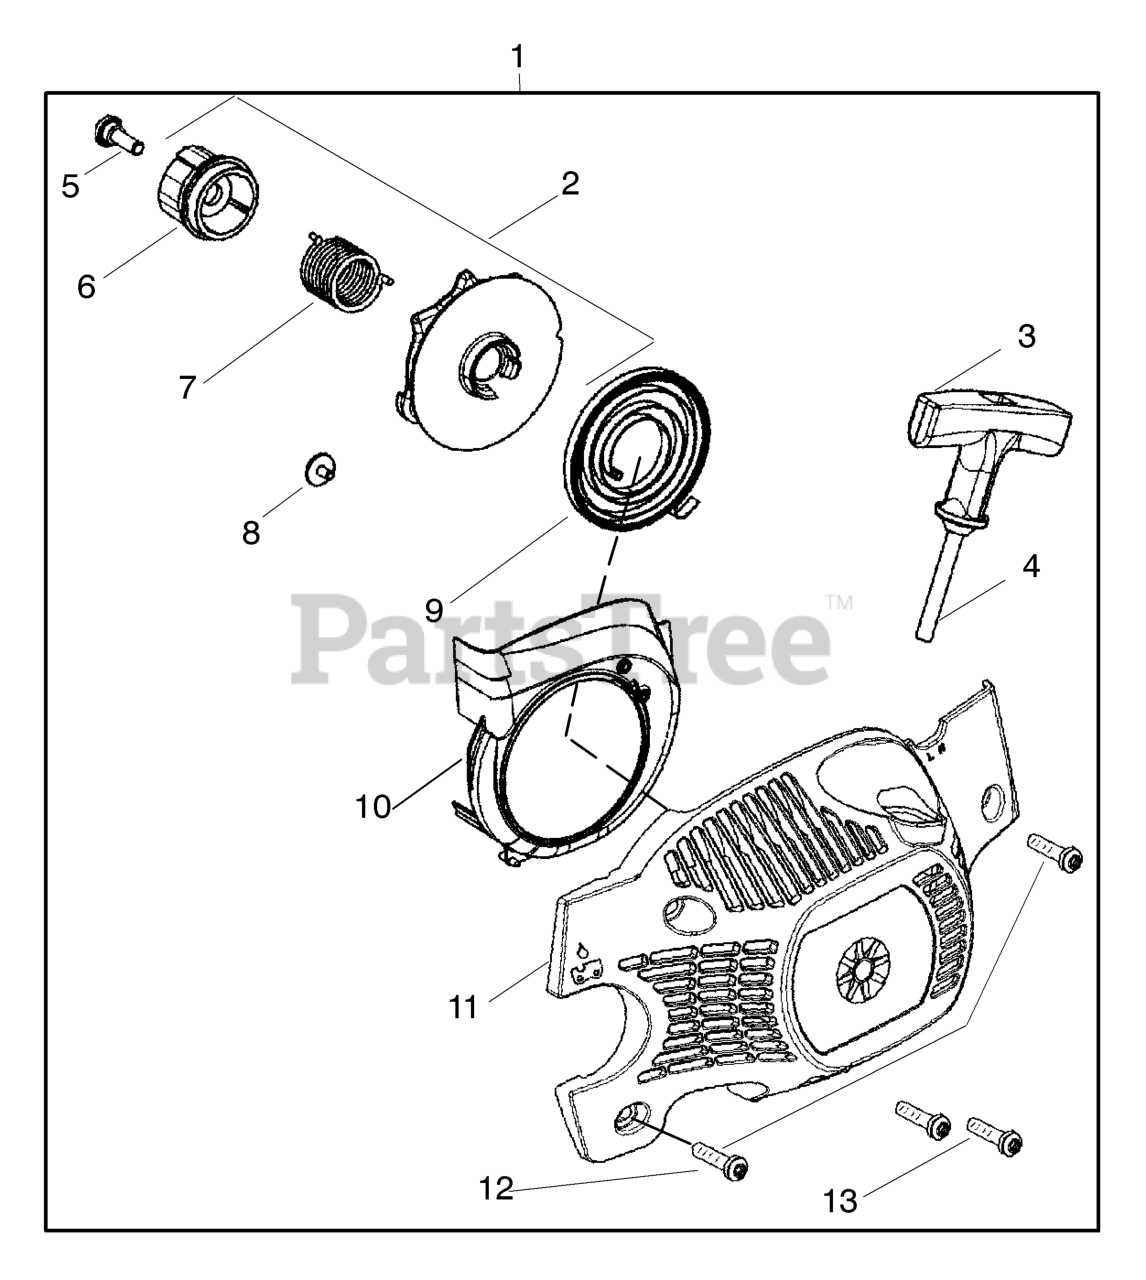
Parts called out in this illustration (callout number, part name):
1	KIT FAN HSG & STARTER EPS
2	KIT EPS STARTER
3	STARTER HANDLE
5	SCREW SHOULDER
6	HUB STARTER EPS
7	SPRING EPS
8	SCREW SEMS TOOTHED WASHER
9	SPRING STARTER
10	BAFFLE AIR
11	HOUSING FAN W/ EYELET
13	SCREW,STRTR CVR 36/41
